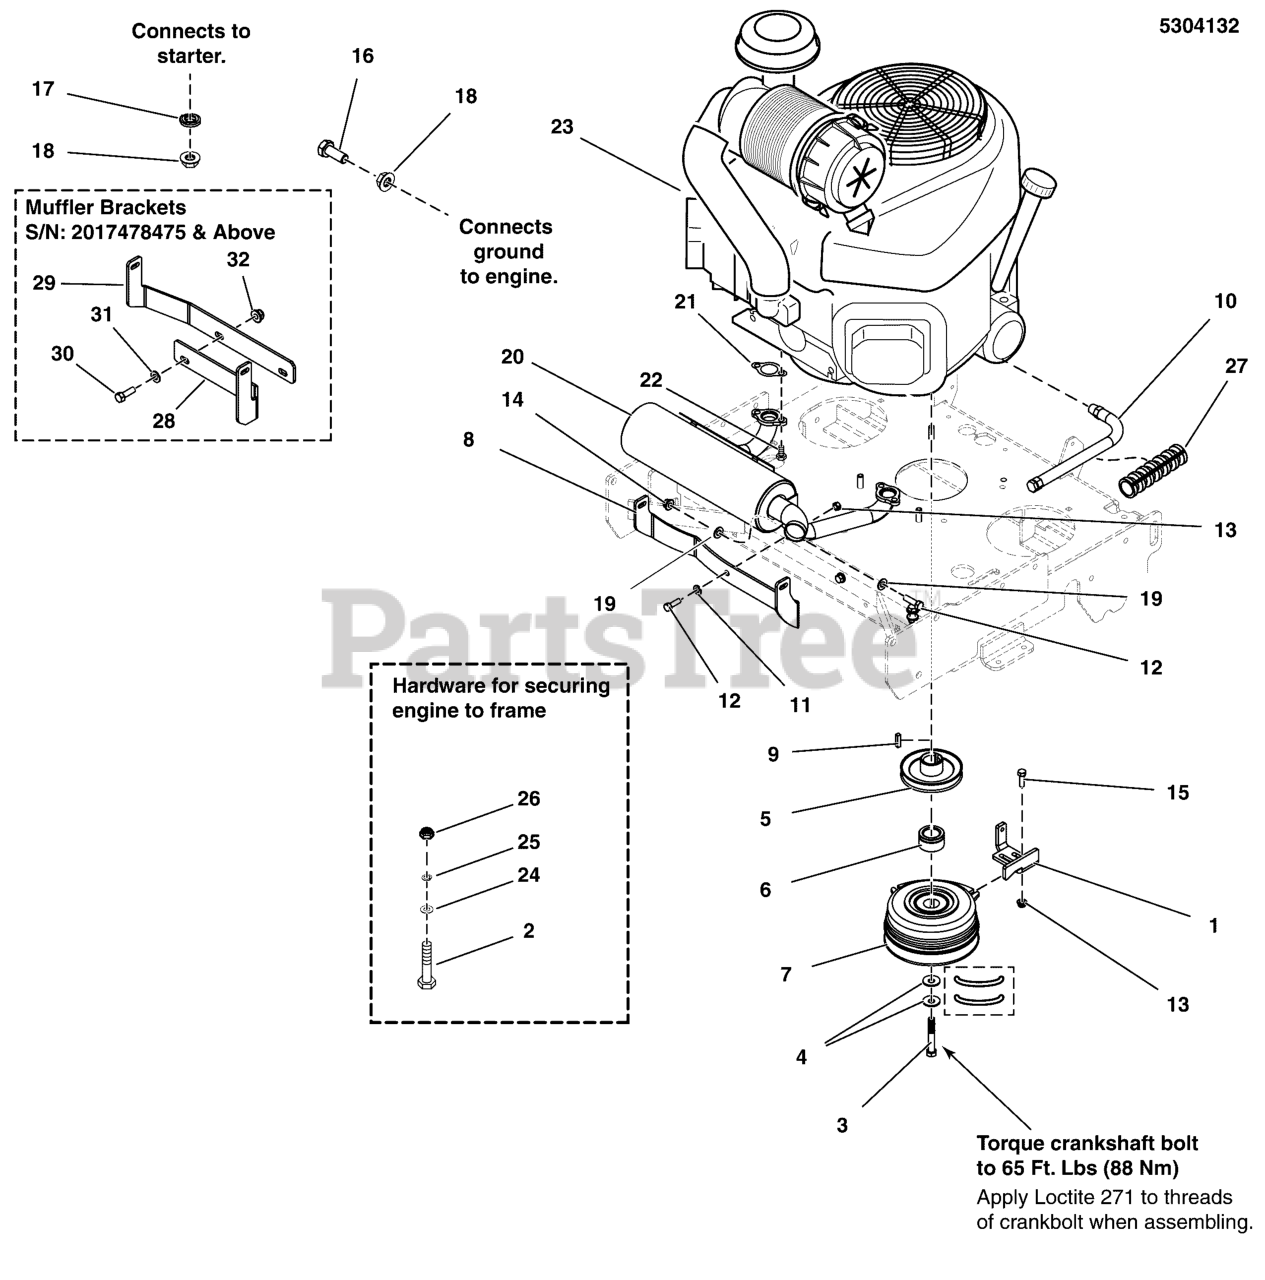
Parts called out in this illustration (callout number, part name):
1	PLATE, CLUTCH ANCHOR - BLK
2	BOLT, 5/16-24 X 1-3/4, GD8
3	BOLT, CRANKSHAFT,7/16-20X2-3/4, GD8
4	BELLEVILLE WASHER 1.1875 X .442 X .089
5	PULLEY, CRANKSHAFT, 1.125ID X 4.50OD, OS
6	SPACER, 1.13 X 1.75 X 1.03, CZ
7	CLUTCH,5218-221, WARNER
8	BRACKET, EXHAUST SYSTEM, WALK - BLK
9	KEY, 1/4 SQ X 1
10	HOSE, OIL DRAIN
11	WASHER, 5/16" SAE
12	BOLT, 5/16-18 X 1 GD5 YZ
13	NUT, 5/16-18 HEX NYLOCK FLANGE
14	NUT, 5/16-18, HEX, CNTR LK,ZINC PHOS/OIL
15	BOLT, 5/16-18 X 1" CARRIAGE
16	BOLT, M8-1.25 X 20MM GD8.8
17	WASHER, 5/16 LOCK CZ
18	NUT, M8-1.25 SERR. FLANGE, CZ
19	WASHER, HARD, F436
20	MUFFLER, 26/28, B&S VANG, TWR/WALK
21	GASKET, EXHAUST
22	SCREW-HEX SEMS LOCK WSHR 5/16-18X0.875
23	ENGINE, B&S, VANGAURD
24	WASHER, 5/16" SAE
25	WASHER, 5/16 INT. TOOTH LOCK
26	NUT, 5/16-24, NYLOCK FLANGE, GD8, CZ
27	WIRE LOOM, 3/4 ID X 8.00" LG
28	PLATE, MUFFLER SUPPORT, LH, W35 - BLK
29	PLATE, MUFFLER SUPPORT, RH, W35 - BLK
30	BOLT, 3/8-16 X 1-1/4" GD5 CZ
31	WASHER, 3/8 SAE
32	NUT, 3/8-16 HEX NYLOCK FLANGE
